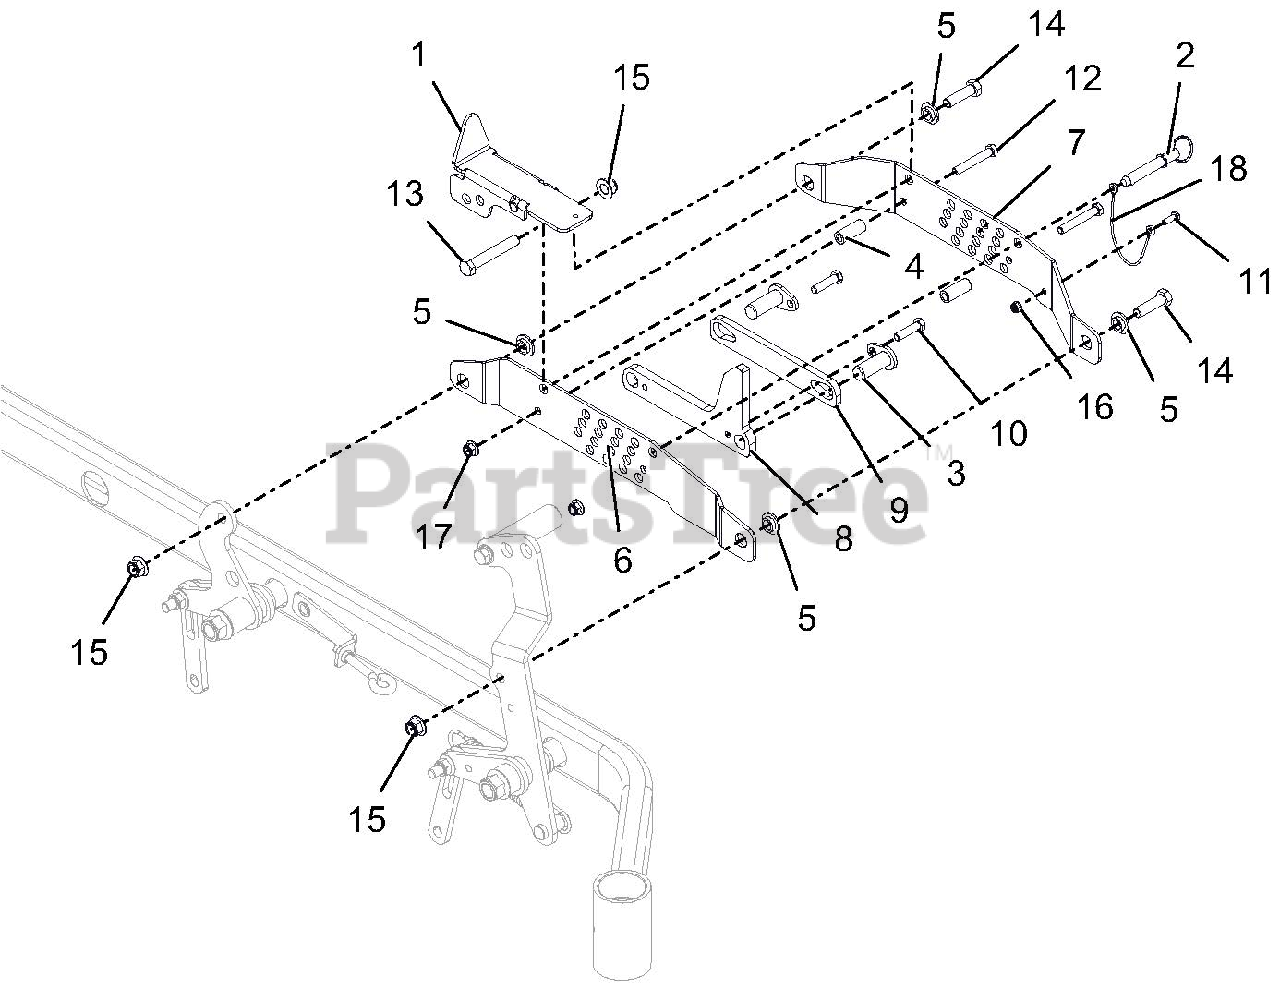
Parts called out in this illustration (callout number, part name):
1	MECHANICAL LOCK-UP WMT - BLACK
2	PIN, .50 X 2.00 USABLE LG BALL
3	WLDMT, PIN HOC MOUNTING
4	SPACER, .375 X .625 X 1.54
5	BSHG-FLG .515X.750X.310X1.120
6	BRKT, RH INBOARD LIFT/CUT HEIGHT-BLACK
7	RH INBRD LIFT/CUT HT BRKT- BLK
8	HOC STOP BRKT - BLK
9	HOC STOP SPACER - BLK
10	BLT,HEX .38-16X1.50 GR5 EP30
11	@BLT-HEX .25-20X.75 GR5 YWZC
12	@BLT-HEX .38-16X2.50 GR5 YWZC
13	@BLT-HEX .50-13X3.25 GR5 YWZC
14	@BLT-HEX .50-13X1.75 GR5 YWZC
15	@NUT-LK-NYL-FLG .50-13 YWZC
16	@NUT-LK-NYL-FLG .25-20 YWZC
17	@NUT-LK-NYL-FLG .38-16 YWZC
18	CABLE, 12.0 LANYARD, NYLON
